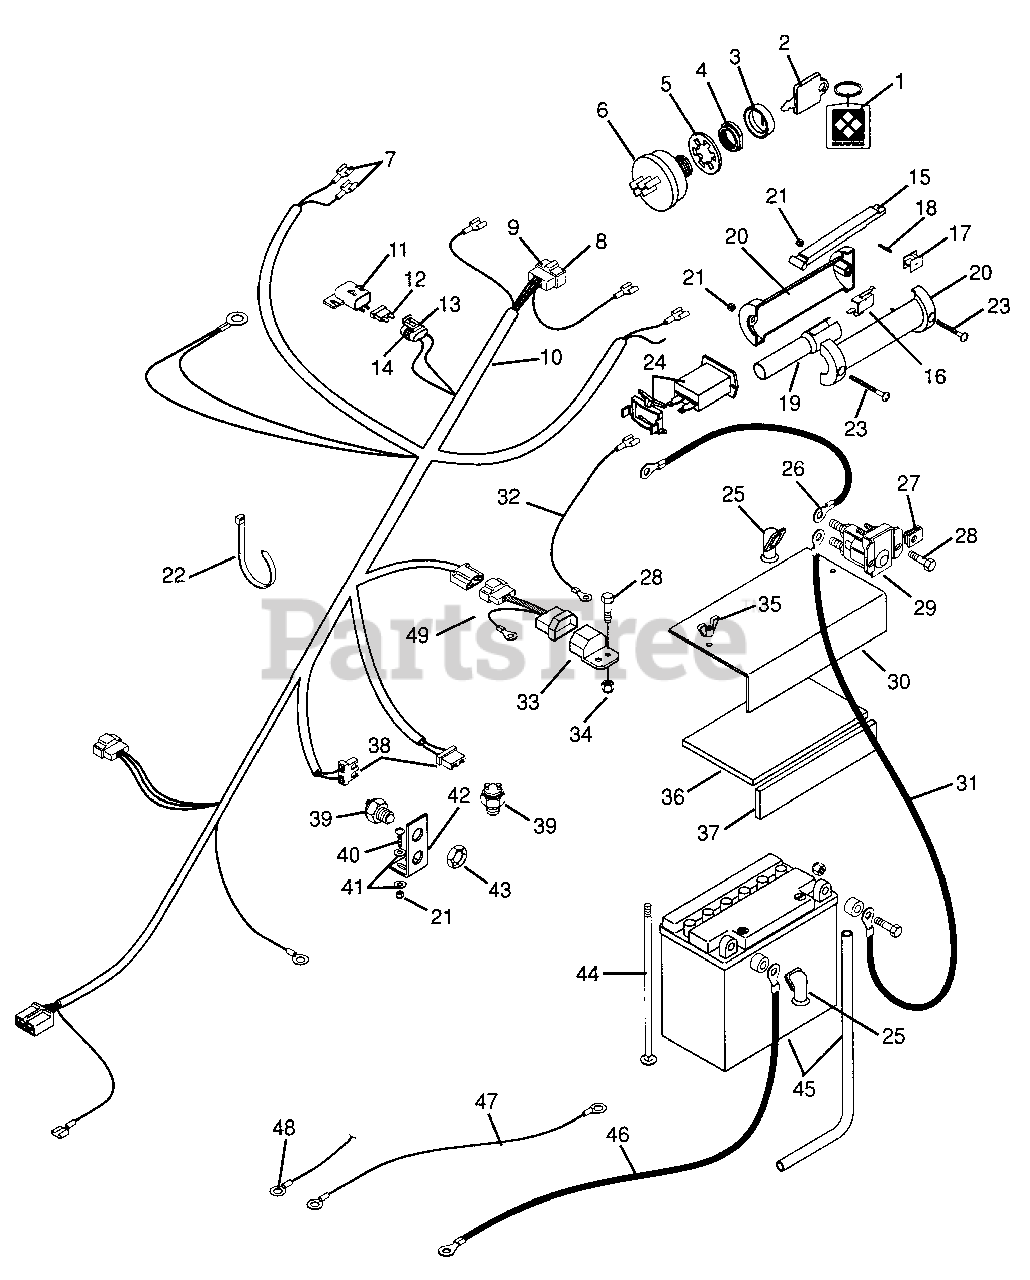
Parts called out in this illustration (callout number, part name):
1	Key Chain
2	Ignition Switch Key
3	Cap, Ignition Switch
4	Nut-Panel .625-32
5	Washer-Lock .625
6	Switch-Key w/Carb. Terminal
7	Terminal, Female
8	Terminal
9	Connector
10	Wire Harness, Pro 200
11	Cover
12	Fuse, 25 AMP
13	Terminal, For 14-16 Ga Wire
14	Assembly, Connector Weather Tight
15	Lever
16	Switch
17	Holder, Switch
18	Pin-Roll .094 x .750
19	Insert, Handlebar
20	Handle, Left Hand and Right Hand
21	Nut-Locking 10-24
22	Tie Wrap, Black
23	Screw-Machine 10-24 x 1.50
24	Hour Meter
25	Boot, Insulator
26	Cable, Starter
27	Nut-Speed .25-20
28	Bolt-Hex .25-20 x .75 Grade 5
29	Solenoid
30	Cover, Battery
31	Cable, Battery to Solenoid
32	Wire, Instrument Panel
33	Interlock Module
34	Nut-Locking-Nylon .250-20 Grade 2
35	Nut-Wing .250-20
36	Pad, Battery
37	Pad, Battery
38	Connector, 2-Wire Switch
39	Switch-Neutral Start N.C
40	Screw-Machine 10-24 x .750
41	Washer-Flat-Steel .219 x .50 x .049
42	Bracket-Interlock Switch
43	Nut-Stamped .56-18
44	Bolt-Round Head Square Neck .25-20 x 7.00
45	Battery, 12 Volt
46	Cable, Negative Battery
47	Wire, Ground
48	Terminal, Ring Tongue
49	Adapter Harness, Interlock
